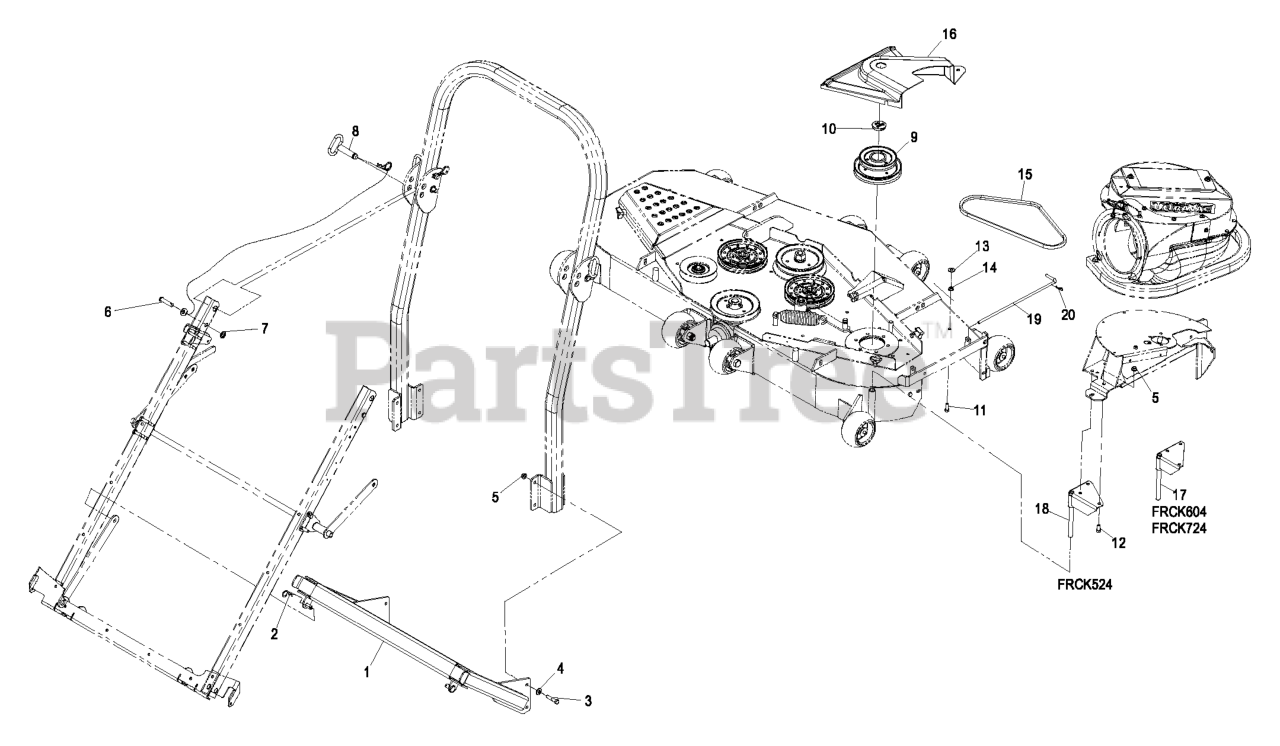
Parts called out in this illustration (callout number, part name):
2	PIN-COTTER
3	SCREW-HH
4	WASHER-BELLEVILLE
5	NUT-HHF, WHIZ
6	PIN-CLEVIS
7	NUT-PUSH
8	PIN-FOLD, ROPS
9	JACKSHAFT, LZUV52
10	PLUG, BLACK NYLON 1.75
11	SCREW-HH
12	SCREW-HH
13	WASHER-FLAT
15	BELT,4L SECTION
16	COVER,FR UV BELT 52
17	PIN-MOUNT
18	WLD,MOUNT PIN FR 52
19	PIN,CHUTE PIVOT
20	PIN-COTTER
